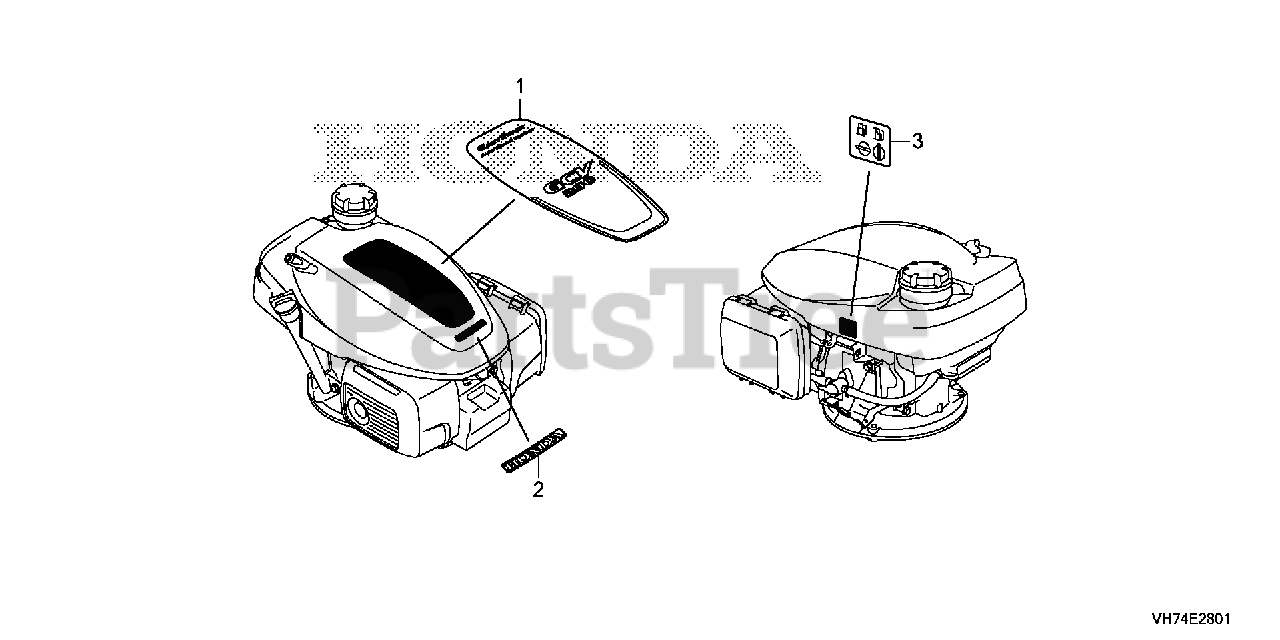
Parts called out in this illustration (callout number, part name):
1	MARK, TOP COVER
2	MARK, HONDA
3	MARK, FUEL PETCOCK
